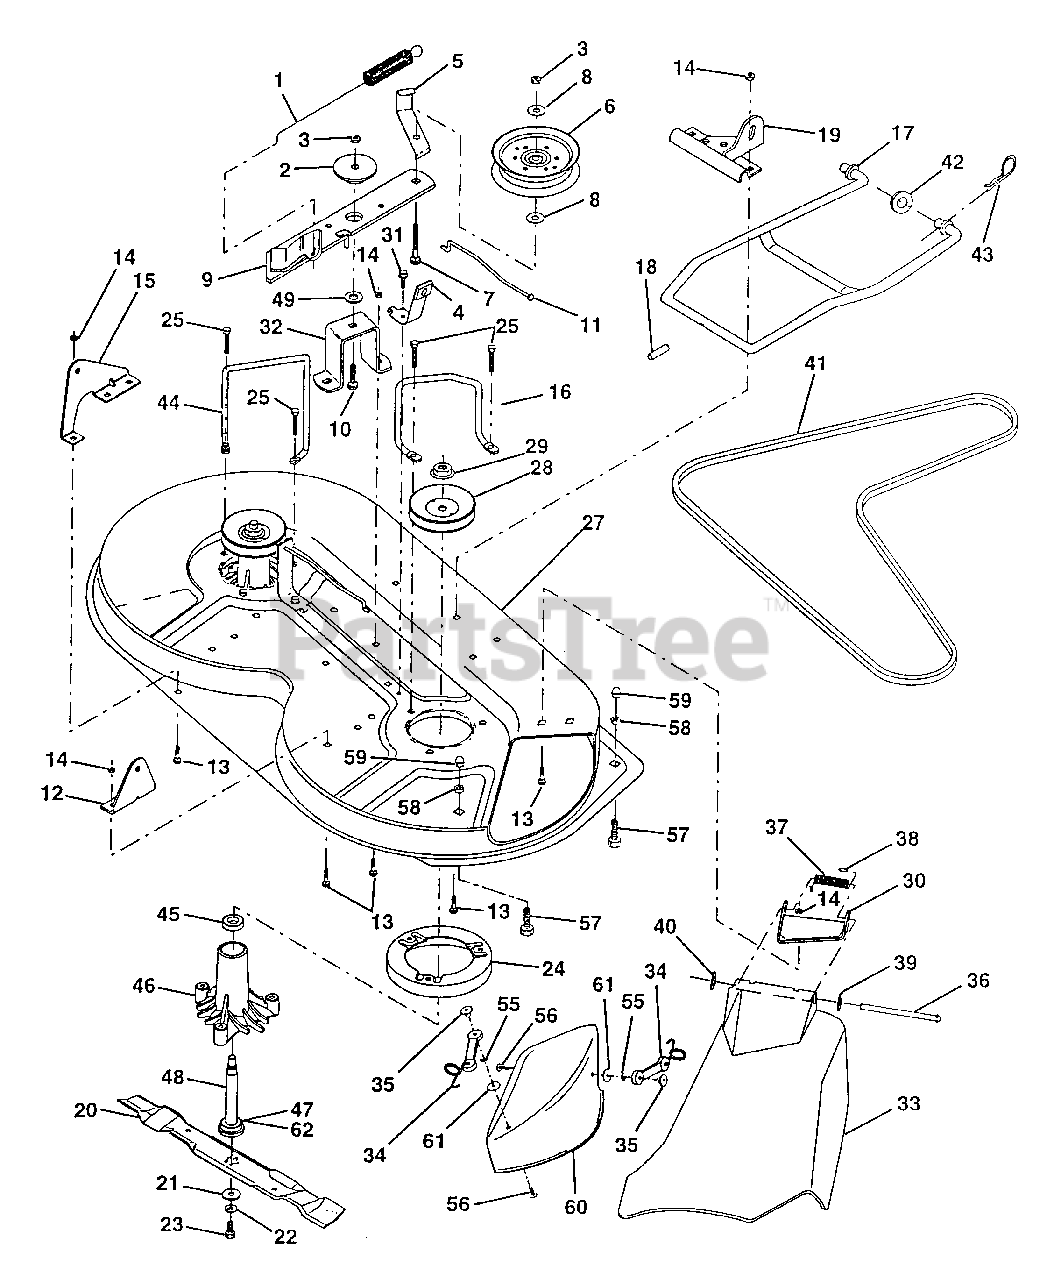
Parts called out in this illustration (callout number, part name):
1	Spring, Mower Clutch
2	Spacer, Retainer
3	Nut, Crownlock 3/8-16
4	Brake Asm.
5	Guide, Belt Idler
6	Pulley, Flat Idler
7	Bolt, Carr. 3/8-16 x 1-3/4 Gr. 5
8	Washer 13/21 x 7/8 x 10 Ga.
9	Arm Asm., Idler Mower (AYP part number)
10	Bolt, Carriage 3/8-16 x 1-1/4
11	Rod, Brake
12	Bracket, Lift R.H. Rear
13	Bolt, Carriage 5/16-18 x 5/8
14	Nut, Crownlock 5/16-18
15	Bracket, Lift L.H. Rear
16	Keeper, R.H.
17	Link, Asm. Mower Stabilizer
18	Pin, Drive
19	Bracket, Asm. Front
20	Blade Mulching
21	Washer, Hard
22	Washer, Lock 3/8 (AYP part number)
23	Bolt 3/8-24 x 1-1/4 Gr. 8
24	Stripper (AYP part number)
25	Screw Thdrol Hex Hd (AYP part number)
27	Deck Assembly
28	Pulley, Mandrel (AYP part number)
29	Nut, Flangelock 9/16
30	Bracket, Asm. Deflector
31	Screw, Hex Wsh. Thdrol. 5/16-18 x 1/2
32	Arm, Support Idler Mower
33	Deflector (AYP part number)
34	Latch Asm. Bagger
35	Nut, Weld .327/.304 #10-24 (AYP part number)
36	Rod, Hinge
37	Spring, Torsion Deflector
38	Cap, Sleeve
39	Washer 11/32 x 5/8 x 16 Ga
40	Pushnut
41	V-Belt
42	Washer 11/32 x 5/8 16 Ga.
43	Retainer, Spring
44	Keeper, L.H.
45	Bearing
46	Housing Mandrel Vented
47	Bearing
48	Shaft, Mandrel (AYP part number)
49	Washer, Hardened (AYP part number)
55	Washer, Lock #10
56	Screw, Truss, Hd, Phil 10-24 X 5/8 (AYP part number)
57	Bolt, Fin, Hex 5/16 x 18 Unc x 1
58	Nut, Nylon Insert 5/16-18
59	Nut, Acorn, Hex 5/16 x 18
60	Cover, Mulching 36 (AYP part number)
61	Washer #10
62	Washer Felt
